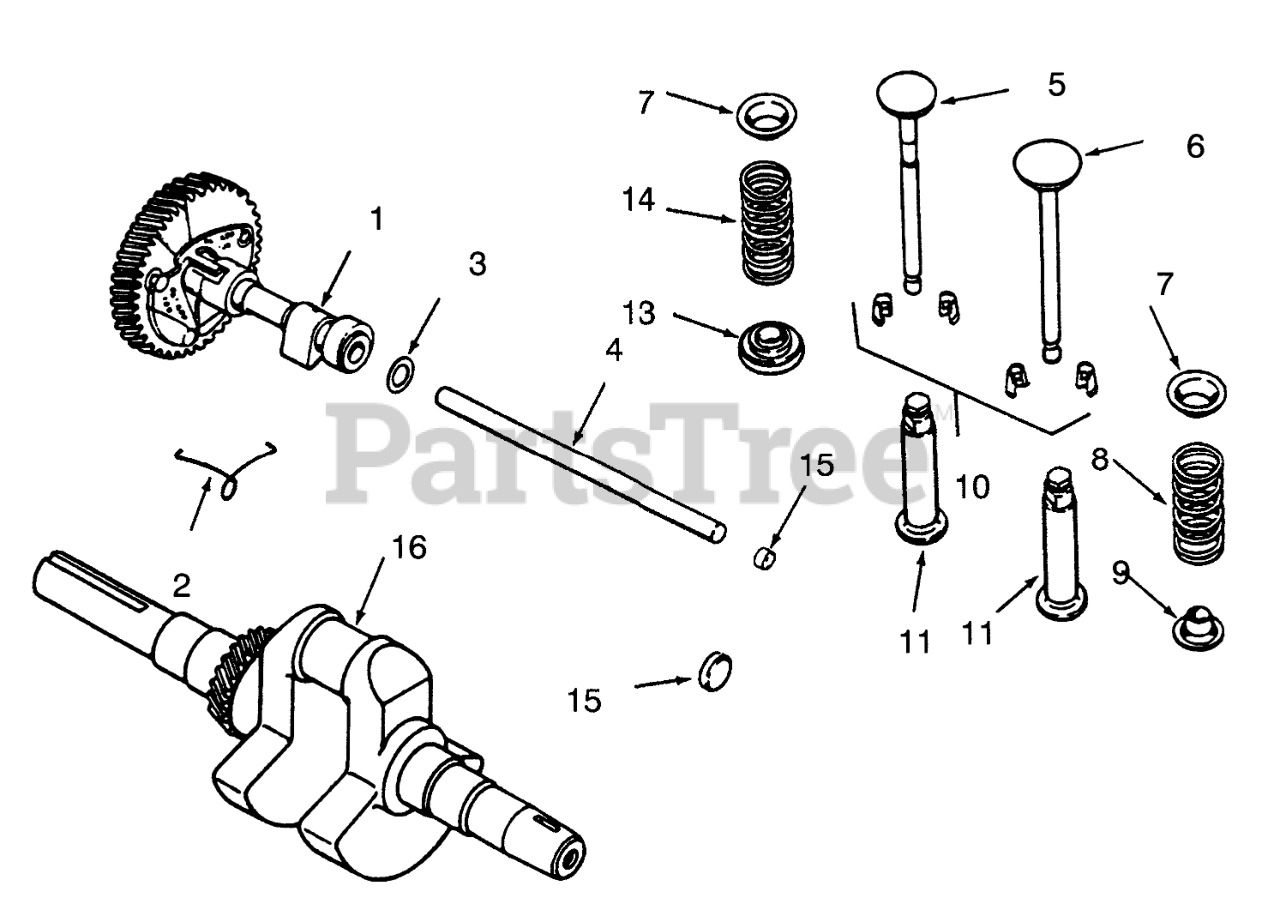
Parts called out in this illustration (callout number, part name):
1	Camshaft Assy (Incl. Ref. #2)
2	Spring
3	Spacer .005
4	Camshaft Pin
5	Valve-Exhaust
6	Valve-Intake
7	UpperSpring Retainer
8	Spring
9	Retainer-Spring
10	Kit-Retainer
11	Tappet
13	Rotator-Valve
14	Spring
16	Kit-Crankshaft (Includes Flywheel Hdwr.)
